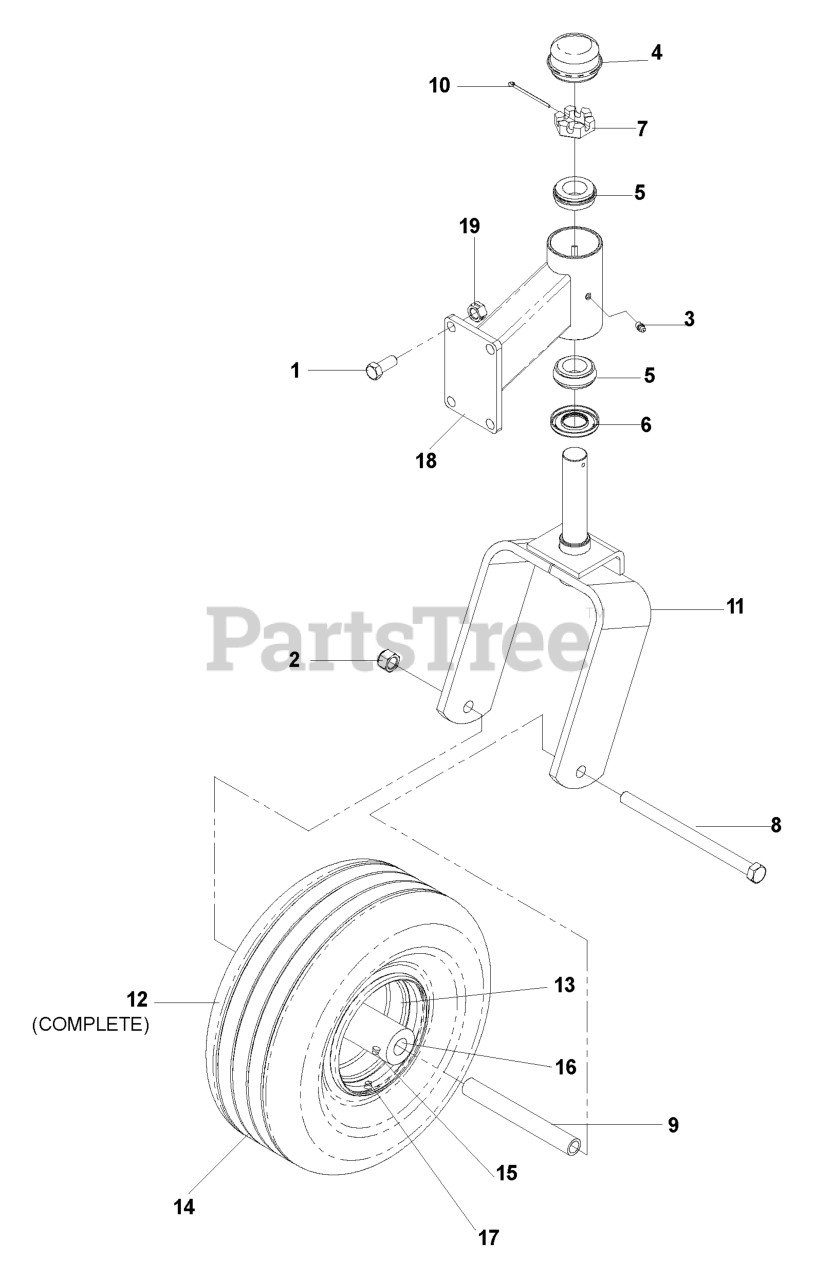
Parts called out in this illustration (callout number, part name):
1	HCS, 7/16-14 X 1, GR5
2	NUT, 1/2-13, NYLOC
3	ZERK
4	CAP GREASE
5	BEARING, ROLLER, TAPERED
7	NUT, 1-14, JAM, SPEC
8	HCS, 1/2-13 X 7 1/2, GR5
10	PIN COTTER, 1/8 X 2
11	CASTER YOKE
12	TIRE, COMPLETE
13	RIM
14	TIRE
17	VALVE STEM
18	CASTER ARM
19	NUT, 7/16-14, CENTERLOCK.\, GR A
